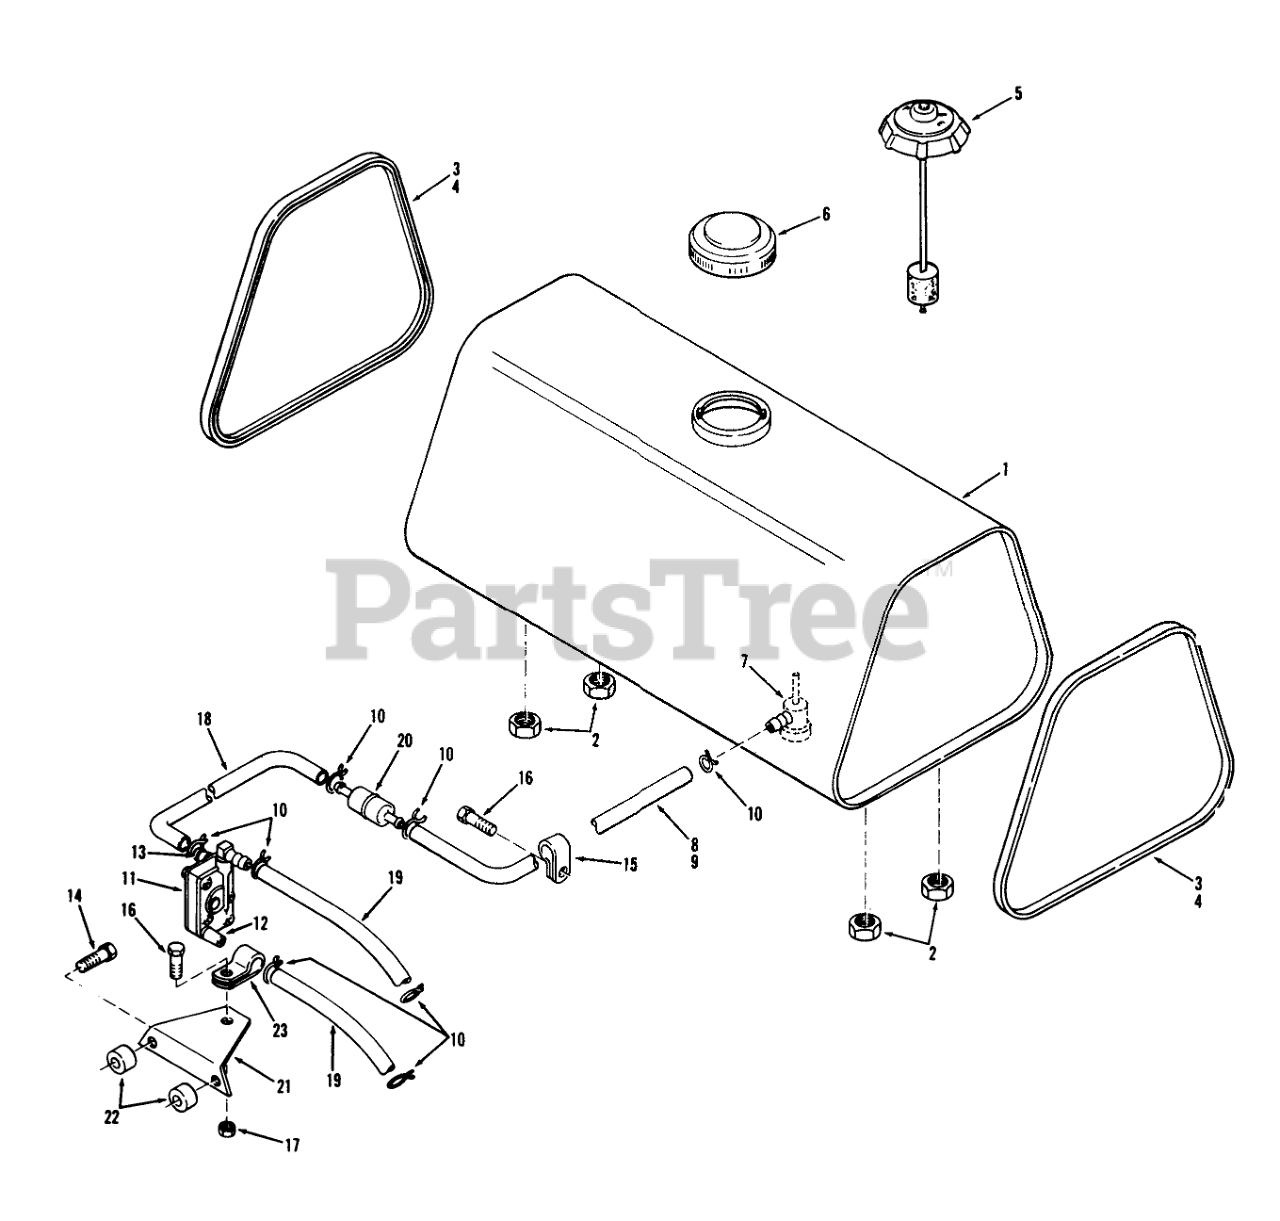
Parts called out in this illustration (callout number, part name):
1	Fuel Tank
2	Flanged Nut
3	Edge Trim
4	GAUGE CAP
5	GAUGE CAP
6	Cap-Tank
7	FILTER & VALVE ASSY
8	Bracket
9	Fuel Line 62
10	Clamp
11	Pump Fuel
12	Coupling
13	FITTING STRAIGHT
14	Bolt
15	CLAMP-HOSE
16	Bolt
17	Nut
19	Skid Bracket
20	Filter
21	Bracket
22	Spacer
23	Clamp
